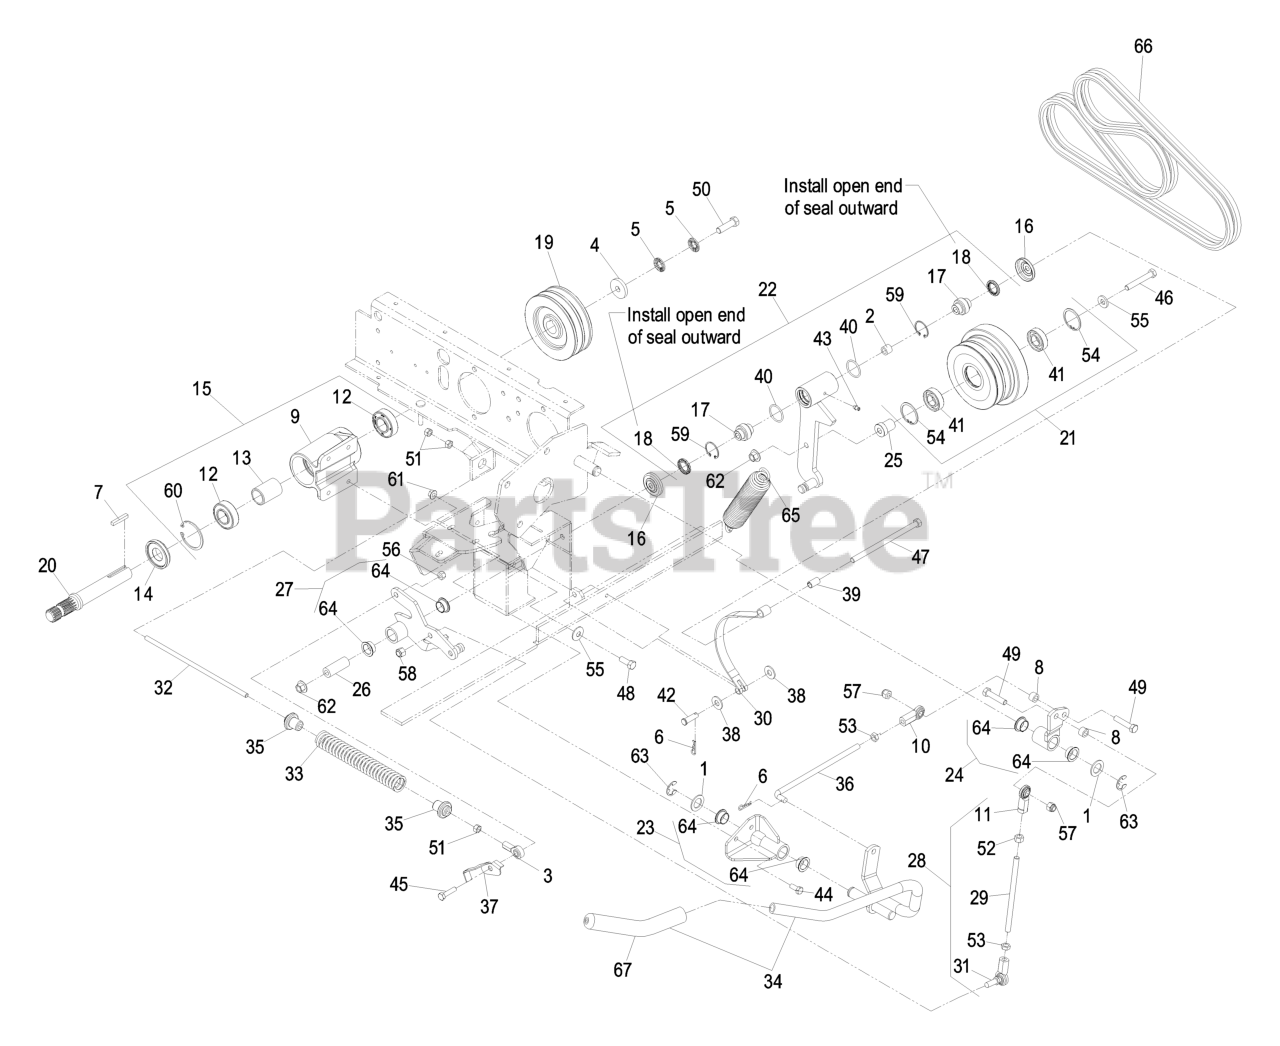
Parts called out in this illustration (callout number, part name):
2	BUSHING-LEVER, LIFT
3	BALLJOINT-RH
4	WASHER-CLUTCH
5	WASHER-SPRING
6	PIN-COTTER
7	KEY-SQUARE
10	JOINT-BALL, END
11	JOINT-BALL END, LH
12	BEARING-JACKSHAFT
13	SPACER-BEARING
14	SPACER-GUARD, BOTTOM
16	GUARD-TOP
17	BEARING-SPHERICAL
18	SEAL-LIP, SINGLE
20	SHAFT-JACK
21	IDLER SHEAVE ASM
22	IDLER PIVOT ASM
23	PIVOT ASM
24	ARM ASM
25	SPACER-IDLER
26	BUSHING
27	ARM ASM
28	CLUTCH LINK ASM
29	ROD-LINKAGE
30	BAND-BRAKE
31	BALLJOINT-RH
32	LINKAGE-ROD, PTO BRAKE
33	SPRING-BRAKE
34	PTO HANDLE ASM
35	BUSHING-SPRING
36	LINK-HANDLE
37	SWITCH-FLAG
38	WASHER-FLAT
41	BEARING-BALL
42	PIN-CLEVIS
43	FITTING-GREASE
44	SCREW-HH
45	SCREW-HH
46	BOLT-CARR
47	SCREW-HH
48	SCREW-HH
49	SCREW-HH
50	SCREW-HH
51	NUT-HEX
52	NUT-HEX, LH
53	NUT-HEX
54	RING-RETAINING
55	WASHER-BELLEVILLE
56	NUT-LOCK, NI
57	NUT-LOCK, NI
58	NUT-LOCK
59	RING-SNAP
60	RING-SNAP
62	NUT-FLANGE
64	BUSHING-BRONZE
65	SPRING-EXTENSION
66	BELTS-MATCHED PAIR
67	GRIP-LEVER, CONTROL
